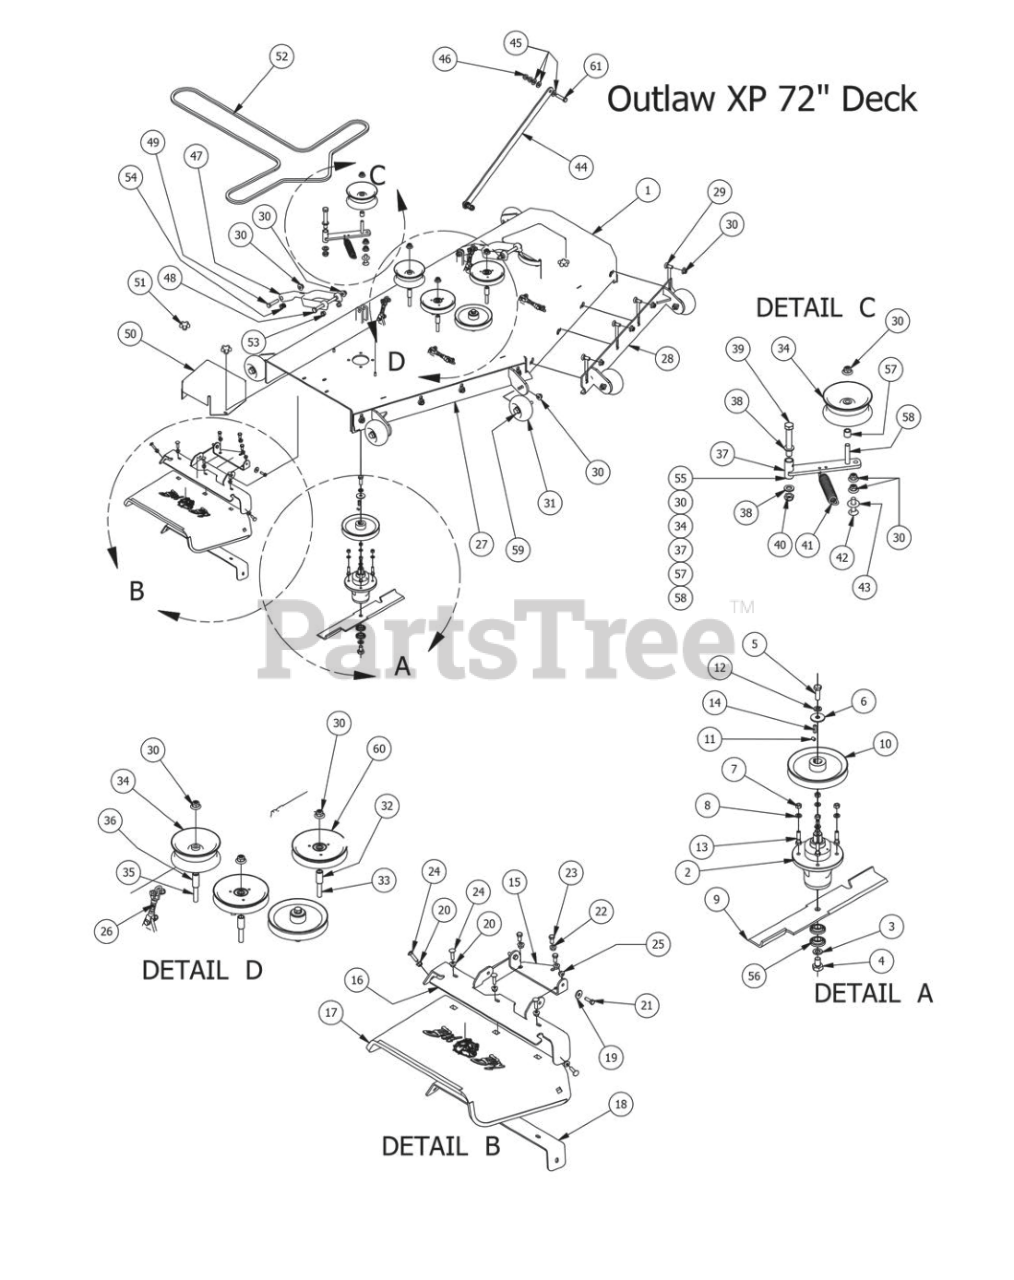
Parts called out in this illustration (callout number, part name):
1	72" Outlaw (Deck Only)
2	Double Bearing Spindle
3	5/8" Lock Washer
4	5/8" x 1 1/2" Grade 8 Bolt
5	1/2"-20 x 1 1/2 - Grade 5 Fine Thread Bolt
6	1/2 Belleville Washer
7	3/8-16 Hex Nuts Zinc
8	3/8 Lockwasher Zinc
9	72" High Lift Fusion Blade
10	7" Deck Pulley
11	5/16 Set Screw
12	1/2" Lock Washer
13	3/8" x 1 1/2" Hex Bolt
14	1/4" x 1" Key
15	Discharge Chute Hanger (deck mounted)
16	60" Upper Discharge Chute Bracket
17	Rubber Discharge Chute
18	60" Lower Discharge Bracket
19	.360 ID Plastic Washer
20	5/16" Flange Nut Zinc W/Serrations
21	5/16" x 1" Bolt
22	3/8" Flange Nut
23	3/8" x 3/4" Hex Bolt
24	5/16" x 1 1/4" Carriage Bolt
25	5/16" Nylon Flange Nut
26	3- Link Adjustable Deck Hange
27	72" Deck Adustable Front (Right)
28	72" Deck Adjustable Front (Left)
29	1/2" x 1 1/4 Carriage Bolt
30	1/2-13 Nylon Insert Flange Nut
31	Deck Wheel
32	.502 ID X.75 OD X 1.500 Leng
33	1/2 x 3 1/2 Flange Bolt Grade 8
34	5 3/4" Deck Idler Pulley
35	1/2" x 4" Bolt (Grade 8)
36	1 3/4" Pulley Spacer
37	Deck Idler Bracket
38	.635 ID Plastic Washer
39	5/8" x 4" Hex Bolt
40	5/8-11 Nylon Insert Jam Half Nut
41	2009 Deck/Pump Idler Spring
42	1/2 x 2" Carriage Bolt
43	1/2" Flat Washer
44	Panhard Linkage Bar
45	.505 Nylon Spacer
46	1/2" Flange Nut
47	Deck Arm Assembly
48	1/2" x 5 1/2" Bolt
49	1/2-13X 2-1/4 GR Hex Bolts
50	72 Spindle Cover
51	5/16" Knob
52	B202 Belt for 72" Outlaw
53	Flange Bushing For Deck Arm upper
54	Flange for Lower Deck Arm
55	Deck Idler Complete Assembly- Componets 30,34,37,57,58
56	Double Bearing For Spindle
57	3/4 OD x 1/2 ID x 3\4 Length
58	1/2-13 x GR 5 Hex Bolt Zinc
59	Deck Wheel Bolt-2011 Outlaw
60	5-3/4 Idler Pulley 72" Decks only
61	1/2-13x2 Grade 8 Hex Bolt
